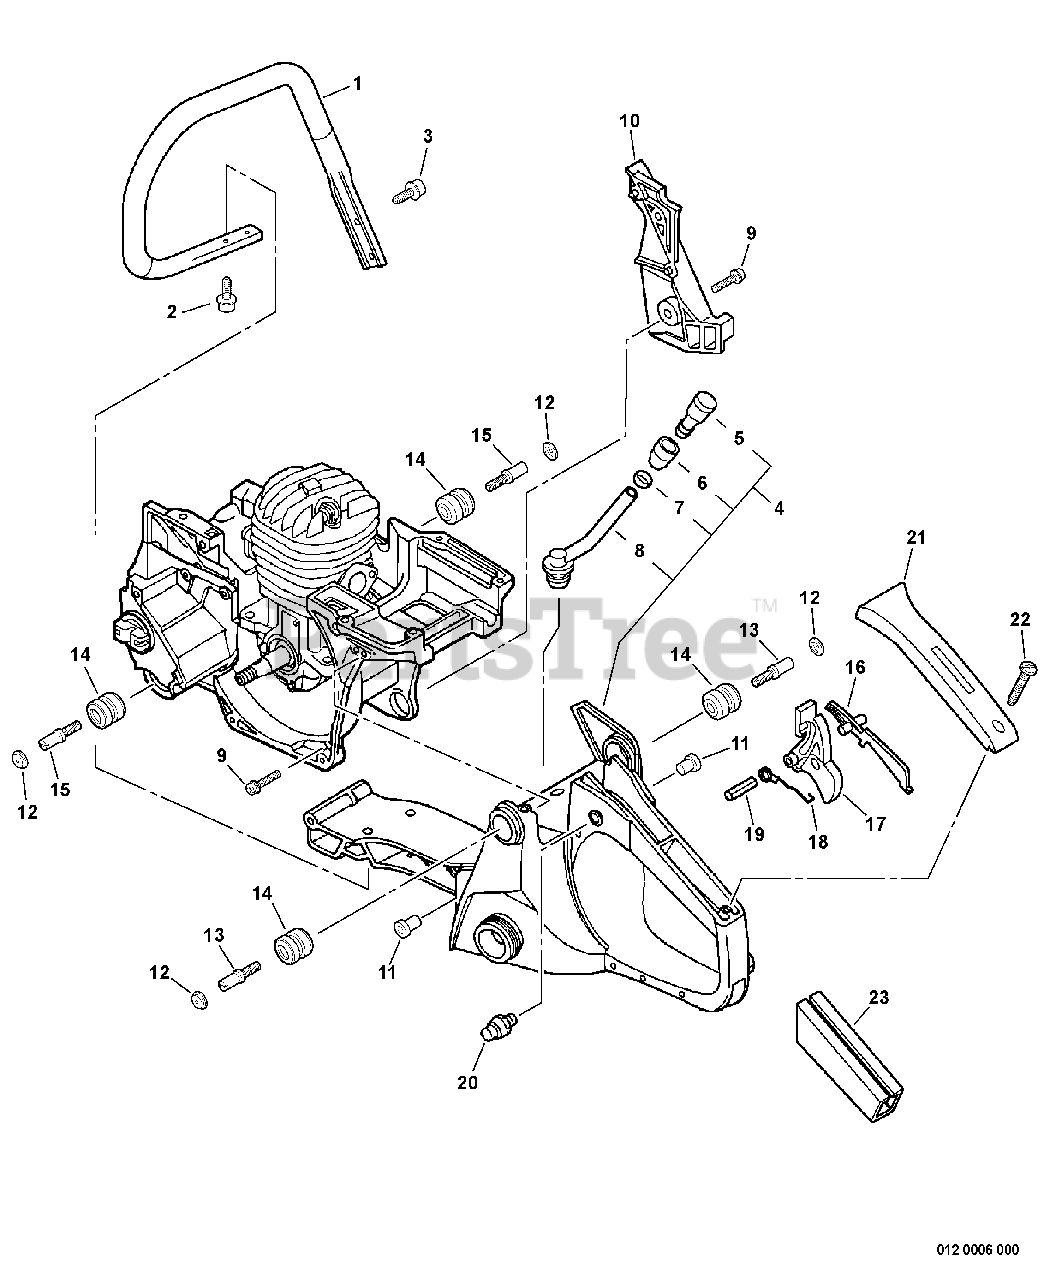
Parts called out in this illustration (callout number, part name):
1	HANDLE, FRONT
2	SCREW TAPPING 5×16
3	SCREW TAPPING 5×20
4	REAR HANDLE ASSY
5	VENT ASSY
6	HOLDER, VENT
7	CLIP Ø6.5 MM
8	PIPE, VENT - GROMMET
9	SCREW 5×16
11	CUSHION 5
12	CAP, CUSHION
14	CUSHION 5
16	LEVER, THROTTLE LOCKOUT
17	TRIGGER, THROTTLE
18	SPRING, THROTTLE RETURN
19	PIN, SPRING 4×30
20	LOCK, THROTTLE TRIGGER
21	COVER, HANDLE
22	SCREW 4×14
23	GRIP, HANDLE
